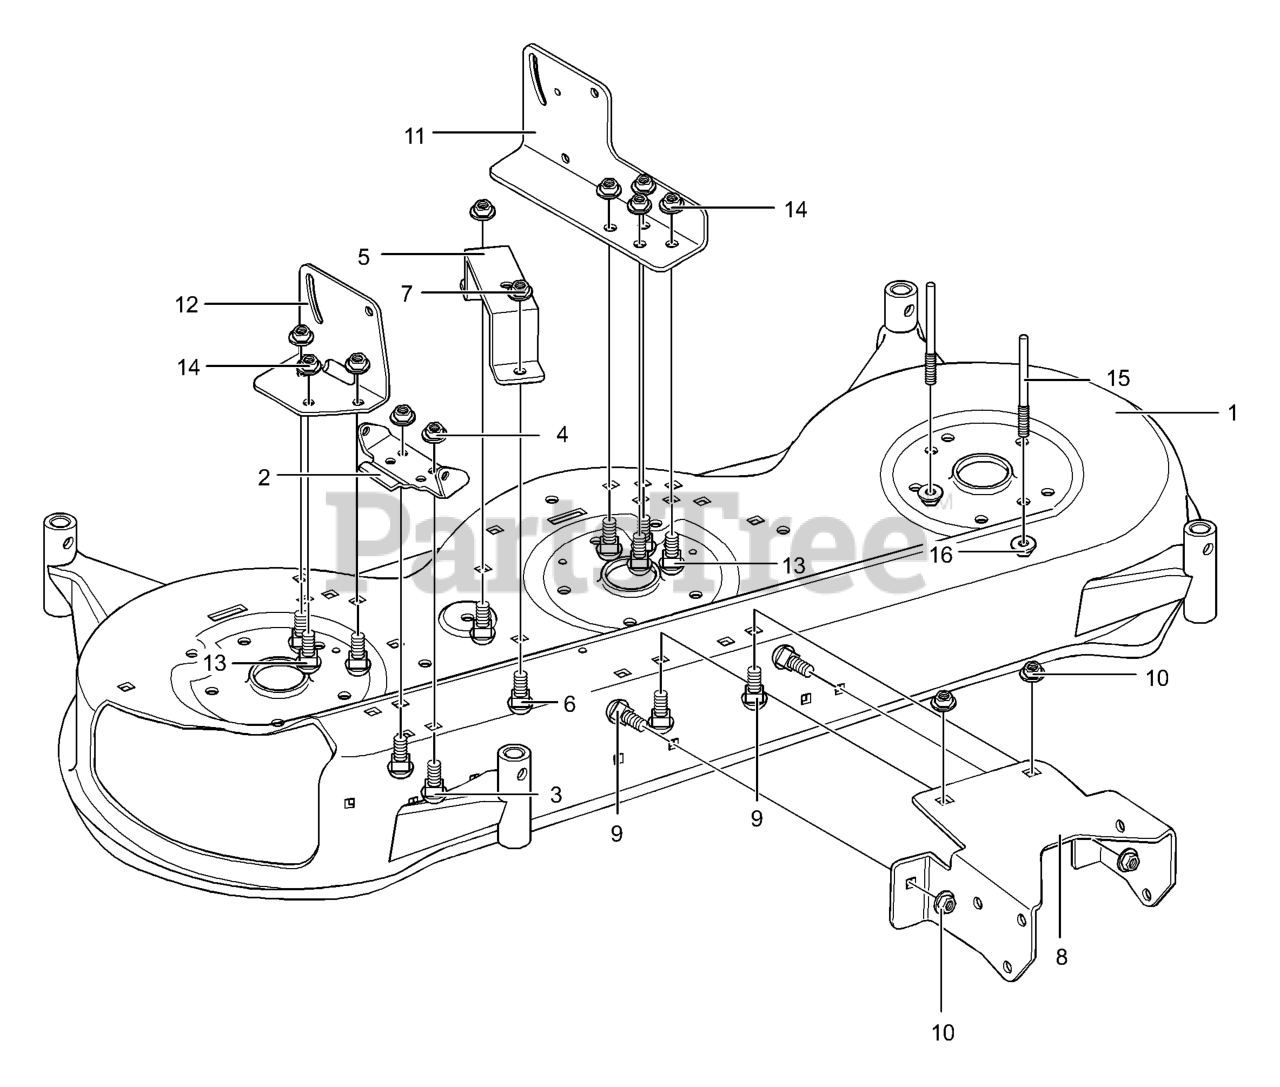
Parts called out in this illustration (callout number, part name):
1	MOWER DECK, 46"
2	HINGE, CHUTE BRACKET
3	BOLT, CARRIAGE
4	LOCKNUT, FLANGE
5	BRACKET, BELL CRANK
6	BOLT, CARRIAGE
7	LOCKNUT, FLANGE
8	BRACKET, FRONT DECK
9	BOLT, CARRIAGE
10	LOCKNUT, FLANGE
11	BRACKET, LEFT LIFTER
12	BRACKET, RIGHT REAR
13	BOLT, CARRIAGE
14	LOCKNUT FLANGE
15	SCREW, GUIDE
16	LOCKNUT, FLANGE
